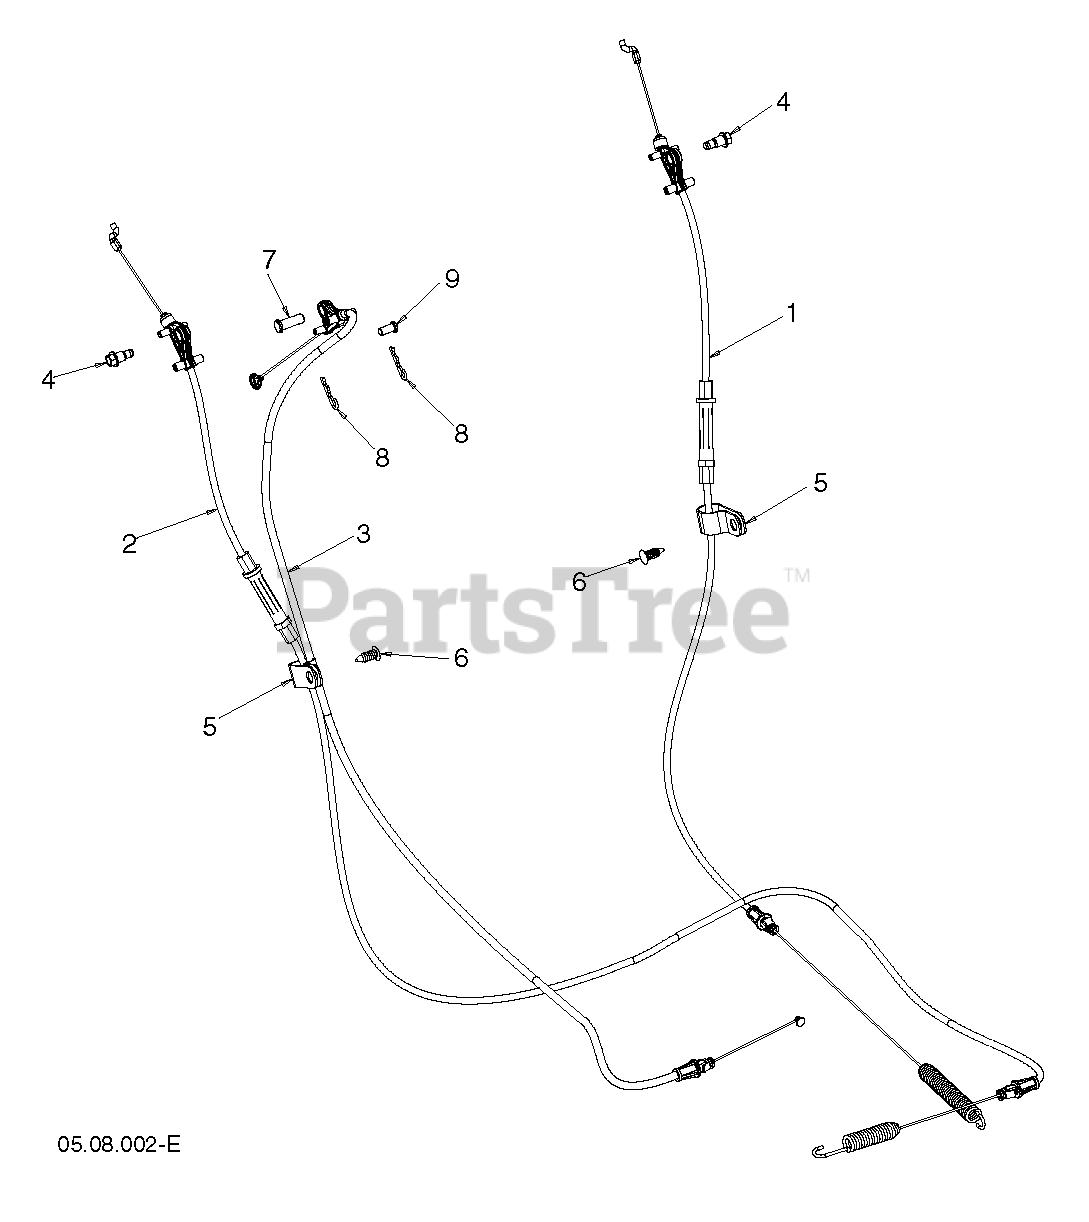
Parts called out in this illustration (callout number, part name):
1	CABLE.CONTROL.DRIVE.DSST.OPP
2	CABLE.CONTROL.AUGER.DSST.OPP.M
3	CABLE.CONTROL.SPEED.DSST.OPP
4	BOLT SHOULDER_1/4-20_TRILOB
5	CLIP.CABLE.BLK
6	FASTENER.PUSH.O.250X0.783
7	PIN CLEVIS 5/16X.875
8	HAIRPIN.SOFT.ZINC.059X1.125
9	PIN CLEVIS .25 X .31
